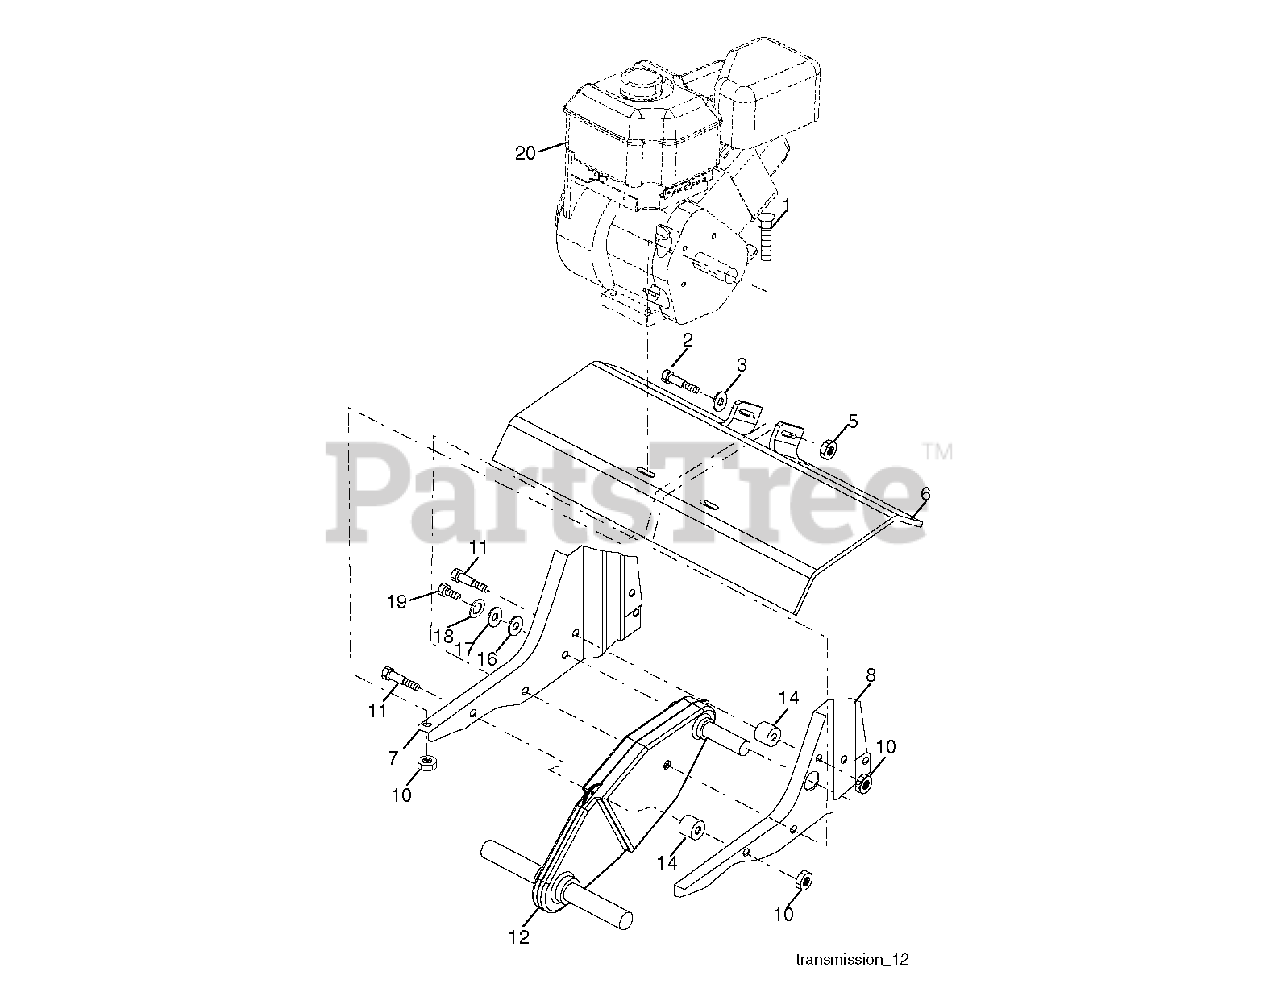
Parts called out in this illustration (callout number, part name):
1	BOLT
3	WASHER
5	NUT LOCK FLG 3/8-16 UNC
7	RP BRACKET, ENGINE, R.H.
8	BRKT.ENGINE.LH.BLACK
10	LOCKNUT-FLANGE 5/16-18
11	BOLT, HEX HEAD 5/16-18 X 2.5
12	TRANSMISSION.ASM.W/1".D-SHAFT
18	LOCKWASHER
